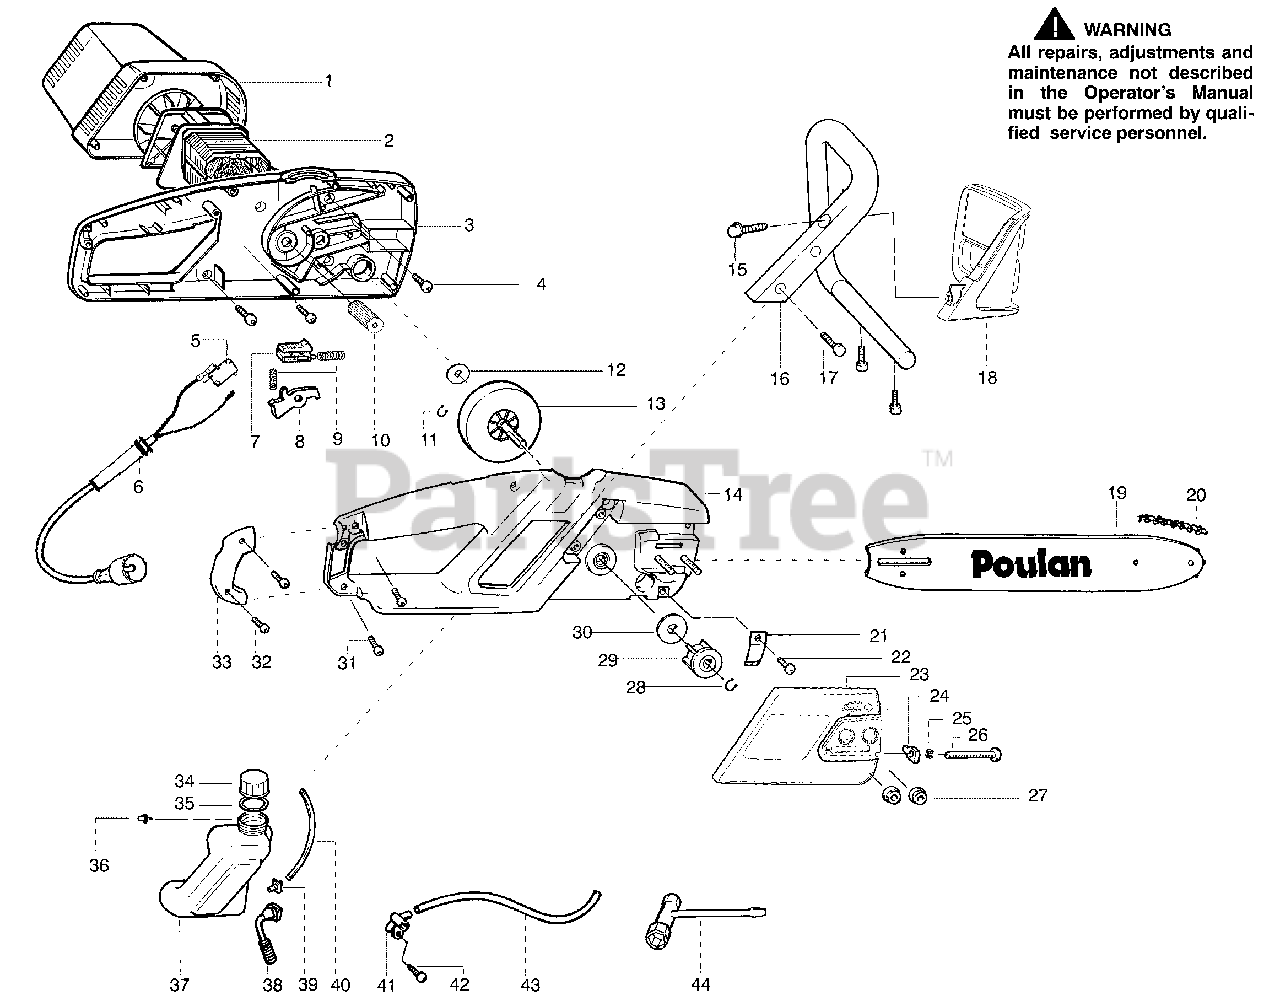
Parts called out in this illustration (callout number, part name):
1	Motor Cover
2	Motor Outline
3	Assy-Housing
5	Switch-Momentary
6	Assy-Harness
7	Lockout Button
9	Spring-Trigger
11	Ring-Retainer
12	Washer-Thrust
13	Gear Drive
14	Housing Cover
16	Front Handle
18	Handguard
20	Chain-16"
21	Chain Catcher
23	Bar Clamp
24	Pin-Bar Adjust
25	Retainer-Bar Ajdust
26	Screw-Bar Adjust
27	Nut-Bar Mounting
28	Ring-Retainer
29	Sprocket (3/8 Pitch)
30	Washer-Sprocket
33	Cover Access
34	Oil Cap
35	O-Ring (Oil Cap)
36	Check Valve (Duckbill)
37	Oil Tank Ass'y.
38	Oil Pickup Ass'y.
39	Oil Pickup Fitting
40	Inlet Line
41	Oil Pump Ass'y.
43	Outlet Line
44	Bar Wrench
